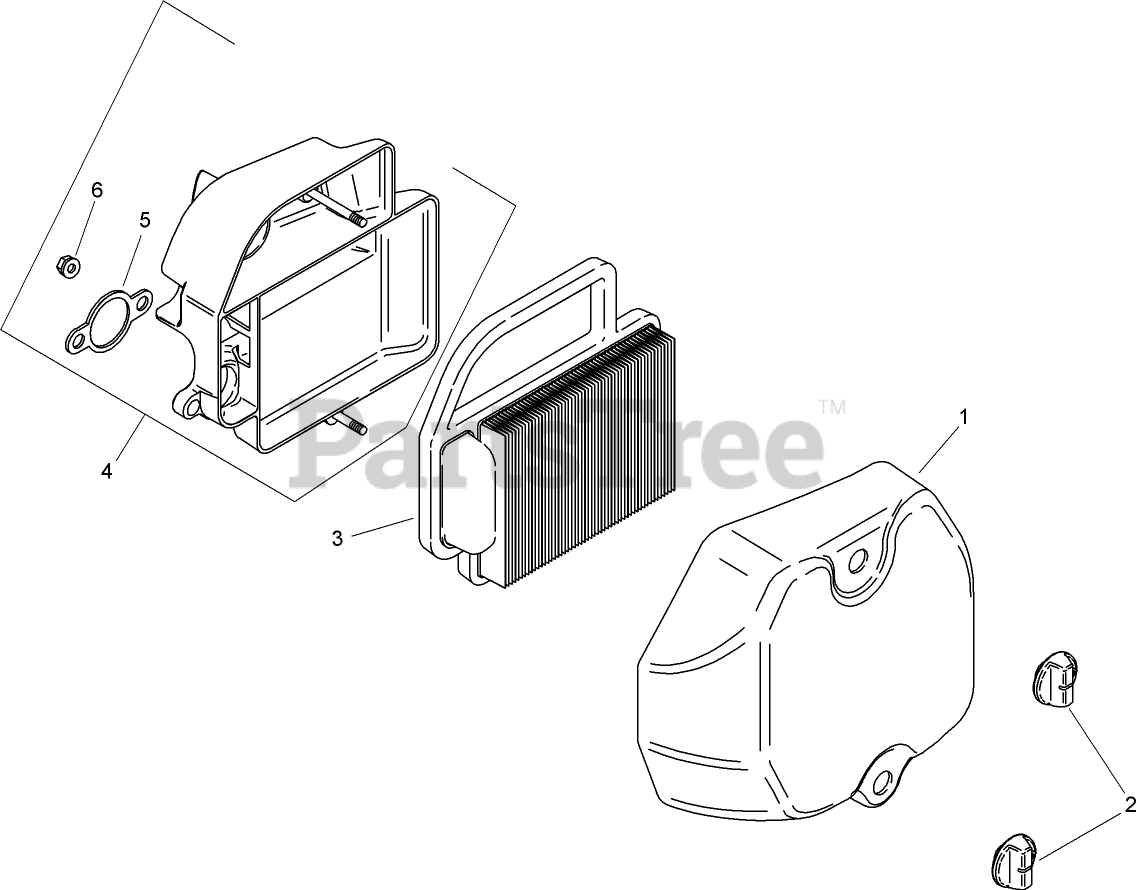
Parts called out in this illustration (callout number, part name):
1	AIR CLEANER COVER ASM
2	KNOB-COVER
3	Element-Cleaner, Air
4	Air Cleaner Base Kit (Includes 5)
5	Gasket-Base, Air Cleaner
6	NUT-FLANGE (M6X1.0)
